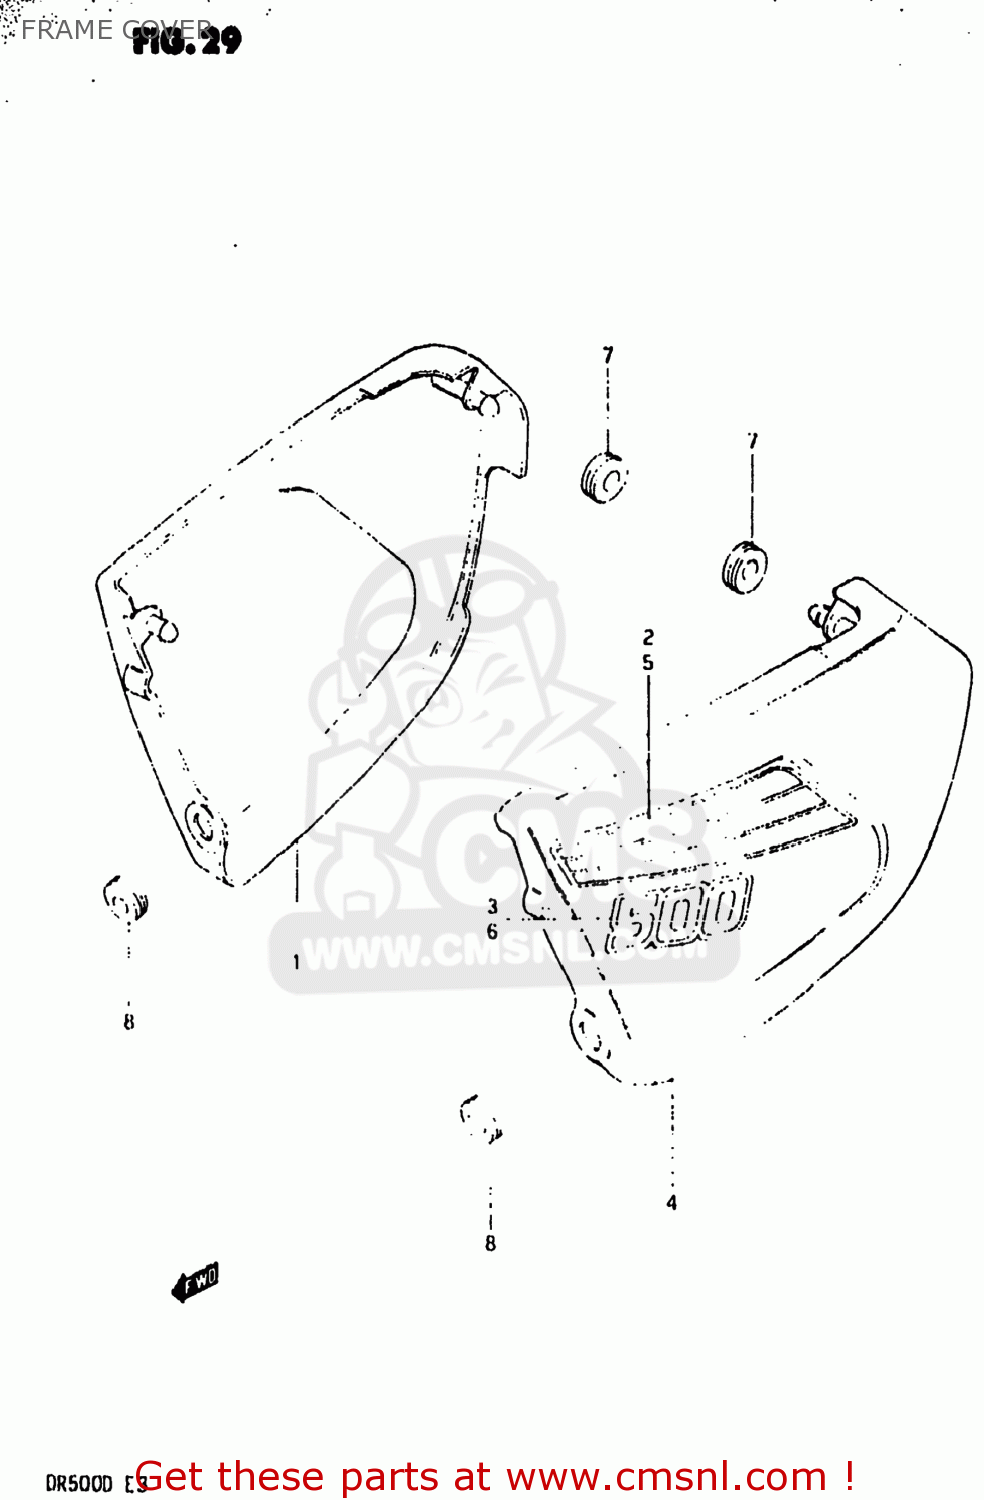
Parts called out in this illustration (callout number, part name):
1	COVER,FRAME,RIGHT
2	TAPE SET,FRAME COVER,RIGHT
3	EMBLEM
4	COVER,FRAME,LEFT
5	TAPE SET,FRAME COVER,LEFT
6	EMBLEM
7	CUSHION
8	CUSHION
